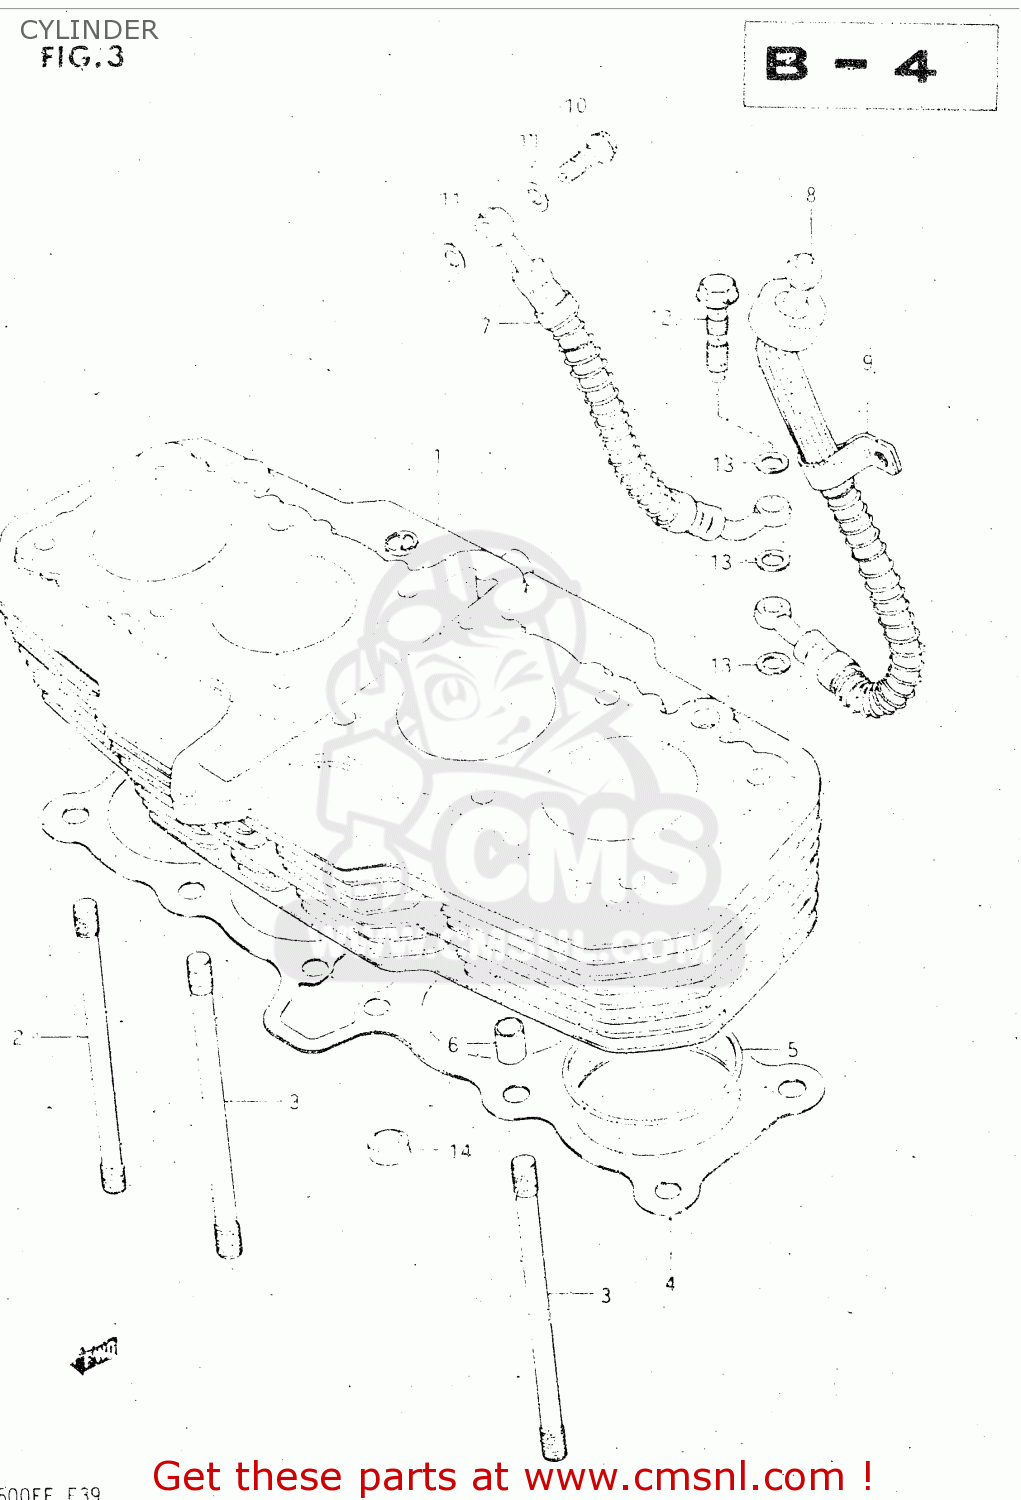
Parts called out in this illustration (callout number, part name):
1	CYLINDER
2	STUD
3	STUD
4	GASKET,CYLINDER (MCA)
5	O RING(D:2,ID:61)
6	PIN
7	HOSE,OIL CRANKCASE,R
8	HOSE,OIL CRANKCASE,L
9	CLAMP,OIL HOSE CRANKCASE
10	BOLT UNION
11	GASKET 8.2X14X1 (NAS)
12	BOLT,OIL PIPE
13	WASHER(10X15X1.5)
14	PAD,CYLINDER HEAD
